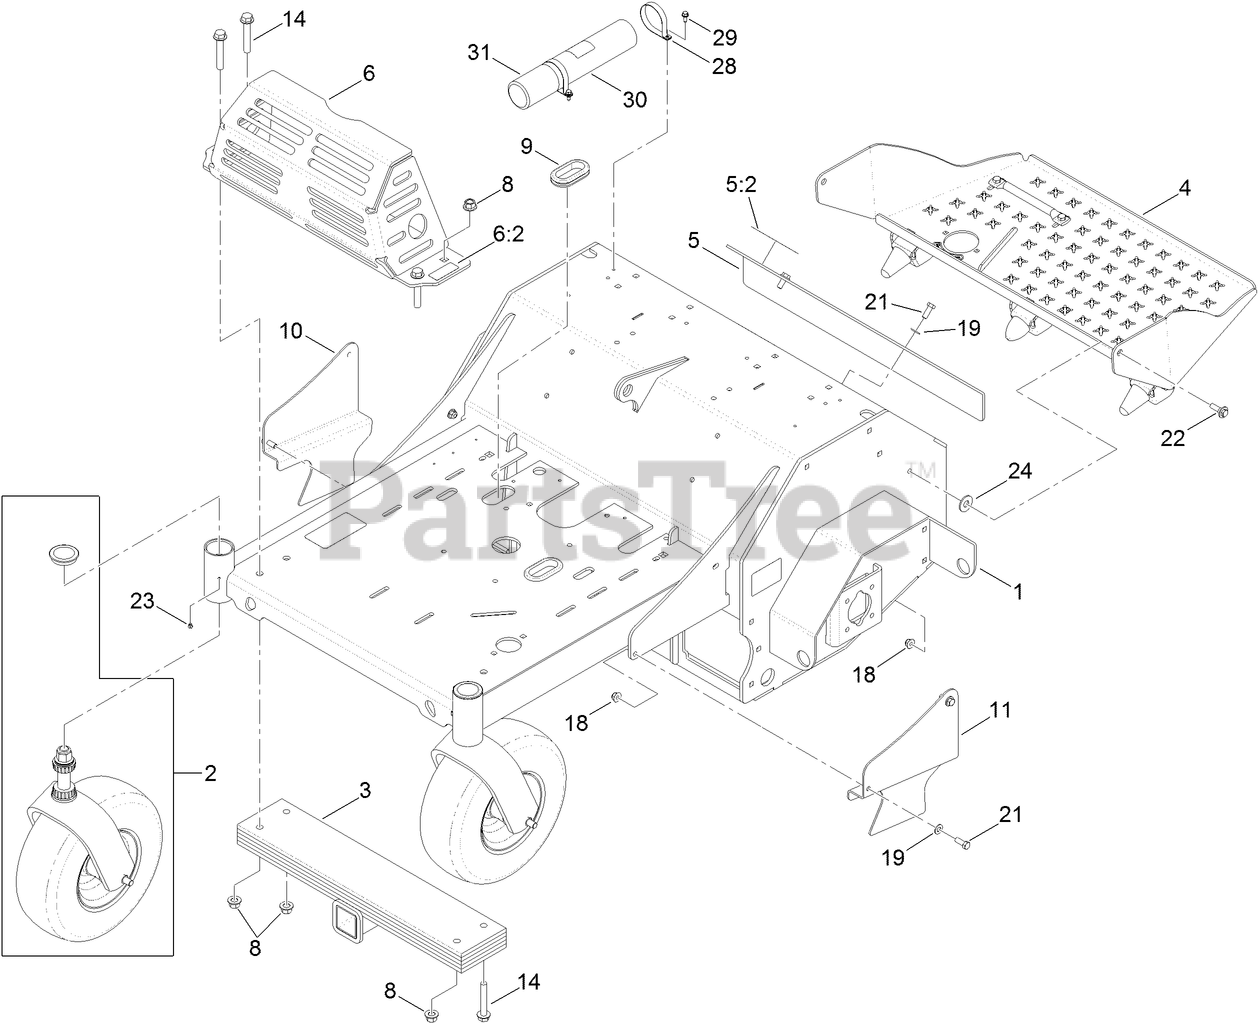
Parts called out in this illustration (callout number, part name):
1	MAIN FRAME ASM
2	FRONT CASTER ASM W/FORK
4	PLATFORM W/ROCKER ASM
5	ACCESS COVER ASM
5:2	DECAL-OPERATION, TINE GROUND (CE)
6	MUFFLER GUARD ASM
6:2	DECAL-SURFACE, HOT
8	NUT-LOCK
9	GROMMET
10	GUARD-CHAIN, RH
11	GUARD-CHAIN, LH
14	SCREW-HF
18	NUT-HF, NI
19	WASHER-FLAT
21	SCREW-HH
22	SCREW-SHOULDER, HWH
24	WASHER-FLAT
28	R-Clamp
29	SCREW-HWH
30	TUBE-MANUAL
31	CAP-HOUSING
